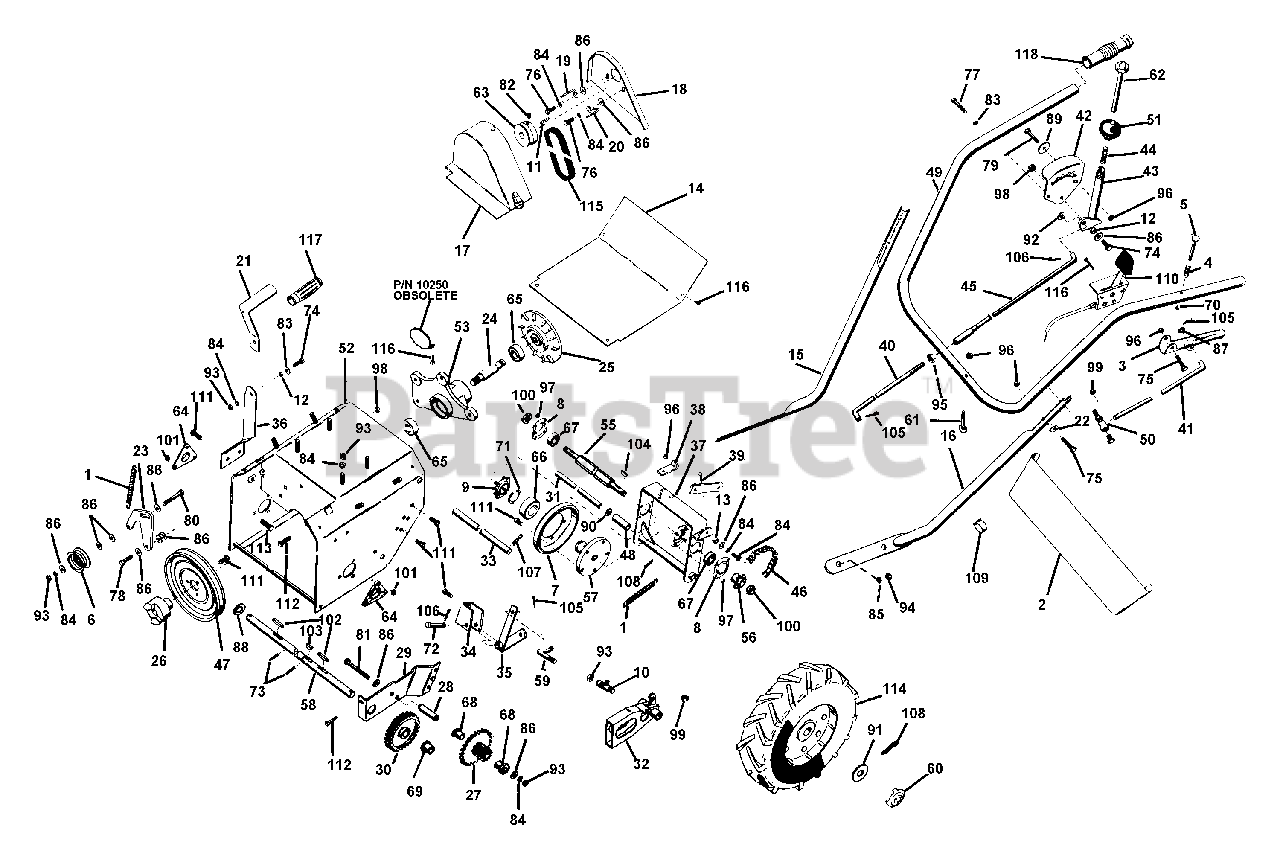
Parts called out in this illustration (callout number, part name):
1	SPRING
2	HANDLE BAR PANEL
3	CLUTCH HANDLE
4	SG-COMP ??X.44X?? WLD 10
5	CLUTCH LOCK PIN
6	IDLER
7	FRICTION DISC
8	BEARING FLANGE
9	BEARING FLANGE
10	BALL JOINT
12	SPACER BUSHING .5 X .32 X .21
13	SPACER BUSHING .5 X .32 X .163
14	BOTTOM COV
15	R H LOWER HANDLE BAR
16	L H LOWER HANDLE BAR
17	OUTER BELT GUARD
18	INNER BELT GUARD
19	R H BELT FINGER
20	L H BELT FINGER
21	CLTCH LEVER
22	HANDLE BAR WASHER
23	IDLER ARM
24	SPINDLE
25	DRIVE PLATE
26	JAW COUPLING
27	PINION & SPROCKET
28	PINION STUB SHAFT
29	SUPPORT BRACKET
30	SPUR GEAR, FELLOWS 35T .750 ID
31	BRACKET PIN
32	SLIDING FORK
33	FORK SHAFT
34	LEVER BRACKET
35	TRANSFER LEVER
36	CLTCH BRCKT
37	DISC BRCKT
38	NEUTRAL CATCH
39	THROWOUT LEVER
40	LOWER SHIFT ROD
41	CLTCH ROD
42	SHIFT QUADRANT
43	SHIFT HANDLE
44	SPRING
45	SHIFT ROD
46	ROLLER CHAIN
49	UPPER HANDLE BAR
50	BALL JOINT
51	SHIFT BALL
52	TRACTOR FRAME
53	BEARING HOUSING
54	6 HP CARB COVER
55	HEX SHAFT
56	9 TOOTH SPROCKET
57	FRICTION DISC HUB
58	AXLE SHAFT
59	CONNECTING LINK
60	HUB CAP
61	ROD HANGER EYEBOLT
62	SHIFT RELEASE HANDLE
63	ENGINE SHEAVE
64	SUPPORT, BEARING
65	BRG-BALL .750X1.750X.50
66	BRG-BALL 1.25X2.18X.63
67	BRG-BALL .500X1.38X.437
68	BSHG-FLG .625X.750X.500X.875BR
69	BSHG-FLG .750X1.000X.625X1.500
70	RG-RTNG-EXT .250X.031
71	RG-RTNG-EXT 1.250X.050
72	CLEVIS PIN
73	PIN-ROLL .250X1.25
74	BLT-HEX .31-18X.63 PL GR 2
75	BLT-HEX .38-16X1.25 PL GR 2
76	BLT-HEX .38-16X1.25 PL GR 2
77	BLT-HEX .38-16X1.25 PL GR 2
78	BLT-HEX .38-16X1.50 PL GR2
79	BLT-HEX .44-14X1.25 PL GR2
80	BLT-HEX .44-14X1.25 PL GR2
81	BLT-HEX .44-14X1.25 PL GR2
82	SCR-SET .38-16X.50 SKHCUP OH
83	WSHR-LK .250X.077 HVY PL
84	WSHR-LK .312X.097 PL HVY
85	WSHR-LK .375X.115 HVY PL
86	WSHR-FL-STL .38X.875X.083 PL
87	BRG-CUP1.980X.420
88	WSHR-FL-STL .531X1.062X.095 PL
89	WSHR-FL-STL .531X1.062X.095 PL
90	BRG-NEEDLE .625X.812X.50
91	WSHR-FL-STL .755X2.000X.125
92	WSHR-FL-STL.406X.812X.065PL
93	NUT-JAM .375-16 PL
94	NUT-JAM .375-16 PL
95	NUT-HEX .312-24 PL
96	NUT-LK-CTR .250-20 PL
97	NUT-LK TOP 10-24 PL
98	NUT-LK .312-18 GR A PL
99	NUT-LK-CTR .312-24 PL
100	NUT-LK-CTR .50-20 PL
101	NUT-LK-FLG .250-20 PL
102	KEY-WDRF .188X.875X.375 SAE11
103	KEY-WDRF .188X.875X.375 SAE11
104	KEY-WDRF .188X.875X.375 SAE11
105	PIN-COTR .09X.75 PL
106	PIN-COTR .12X1.0 PL
107	PIN-COTR .09X.75 PL
108	PIN-COTR .09X.75 PL
109	THROTTLE CONTROL
110	THROTTLE CONTROL
111	BLT-SERHFWH .31-18X.50 PL
112	BLT-SCRHFWH .38-16X.50 PL
113	SCR-SLTR-SERNK .25-20X.62 PL
115	V-BELT, 4L-WRAPPED
116	SCR-TAP 10-12X.50 CRPH PL A
118	GRIP
